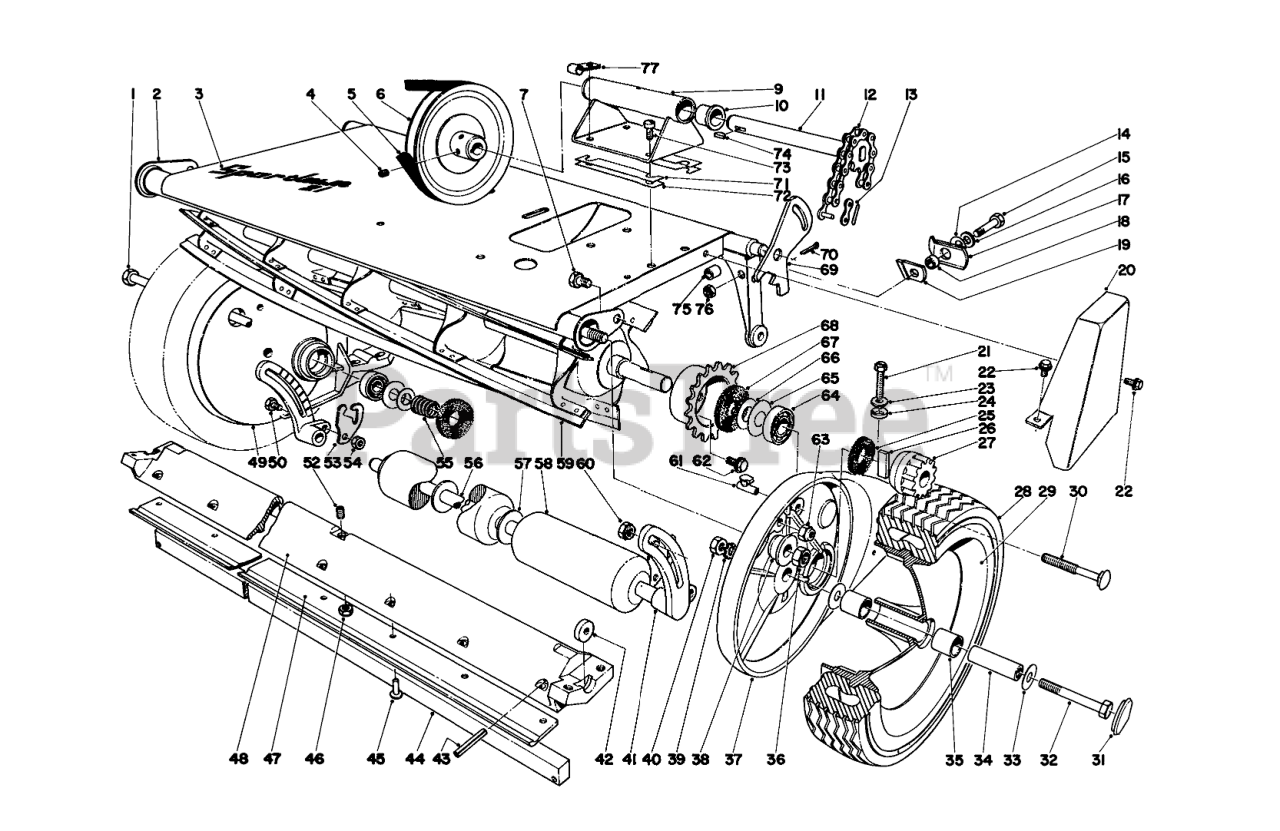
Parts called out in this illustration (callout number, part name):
1	Tie Rod
2	Platform W.A.
3	Decal
3	Decal-Lo-Cut
4	SCREW-SET, HSH
5	V-Belt
6	Pulley
7	SCREW-HH
9	Countershaft Housing (Incl. Ref. 10)
10	BUSHING
11	COSHAFT ASM
11	Countershaft
12	ROLLER DRIVE CHAIN
13	CONNECTING LINK FURN
14	7/16 SPRING WASHER
15	Screw
16	WASHER-PLAIN
17	Stop Lever
18	Spacer
20	CHAIN GUARD
21	ADJ SCREW
22	SCREW-HH
23	U SPHER WASHER
24	L SPHER WASHER
25	FELT WASHER
26	RATCHET DOG
27	Pinion Kit-Left & Right (Incl. Ref. 25)
28	10-1/2 TIRE
29	Wheel Assy. (Incl. Ref. No. 35)
30	BOLT-CARRIAGE
31	Plug Button
33	WASHER
34	Spindle
35	BUSHING
36	NUT-HEX
37	Side Plate Assy., L.H. (Incl. Items 61 & 64)
38	Spacer
39	WASHER-LOCK/EXT
40	NUT-JAM
41	Roller Bracket Kit
42	Bed Bar Pivot
43	PIN-ROLL
44	Adjusting Bar
45	.125 X 3/4 POP RIVET
45	Rivet
46	Nut
47	BEDKNIFE
47	Bed Knife-Lo-Cut
48	Bed Bar
48	Bed Bar Assy. (Incl. Ref. 43 thru 48 & 52)
49	Side Plate Assy., R.H. (Incl. Ref. 61 & 64)
50	SCREW-HH
52	SCREW-SET, HSH
53	GRASS CATCHER HOOK
54	1/4-28 NYLOK NUT
55	Spring
56	ROLLER SHAFT
56	Shaft
57	WASHER-FLAT
58	ROLLER
59	Reel Assy.
59	Reel (Lo-Cut)
61	Oiler
62	Screw
63	NUT-LOCK NI
64	BALL BRG
65	BEARING SEAL
66	Washer
67	Washer
68	Reel Sprocket
68	Sprocket
69	Handle Bracket
70	PIN-COTTER
71	COSHAFT SHIM
73	Fil. Hd. Mach. Screw
74	Woodruff Key
75	Spacer
76	NUT-LOCK NI
77	R-CLAMP
